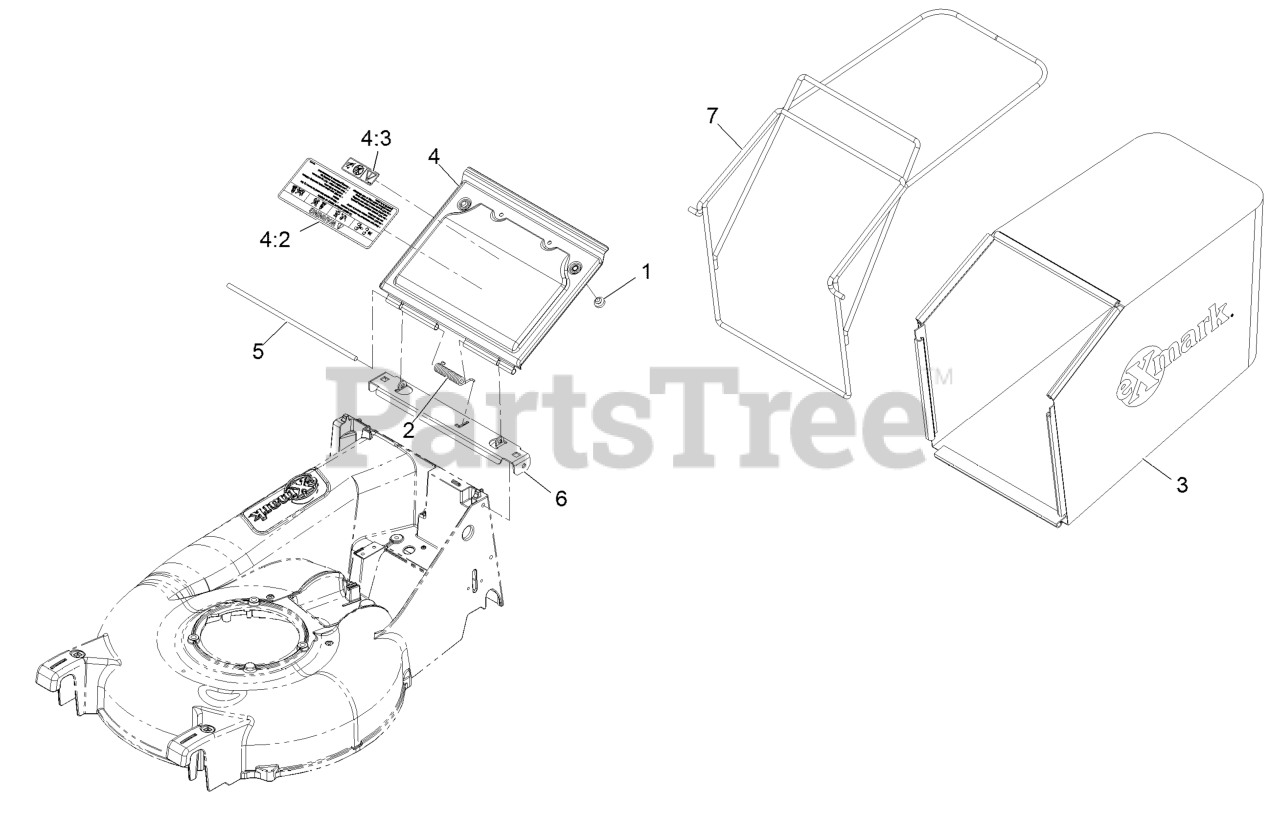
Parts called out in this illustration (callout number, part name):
2	SPRING-TORSION,COVER
3	BAG,GRASS P21
4	DOOR W/DECAL
4:2	DECAL-WARNING DOOR LG
4:3	DECAL-WARNING, BLOCK
5	ROD,DOOR PIVOT
6	BRACKET-DOOR P21
7	WLD,BAG FRAME
